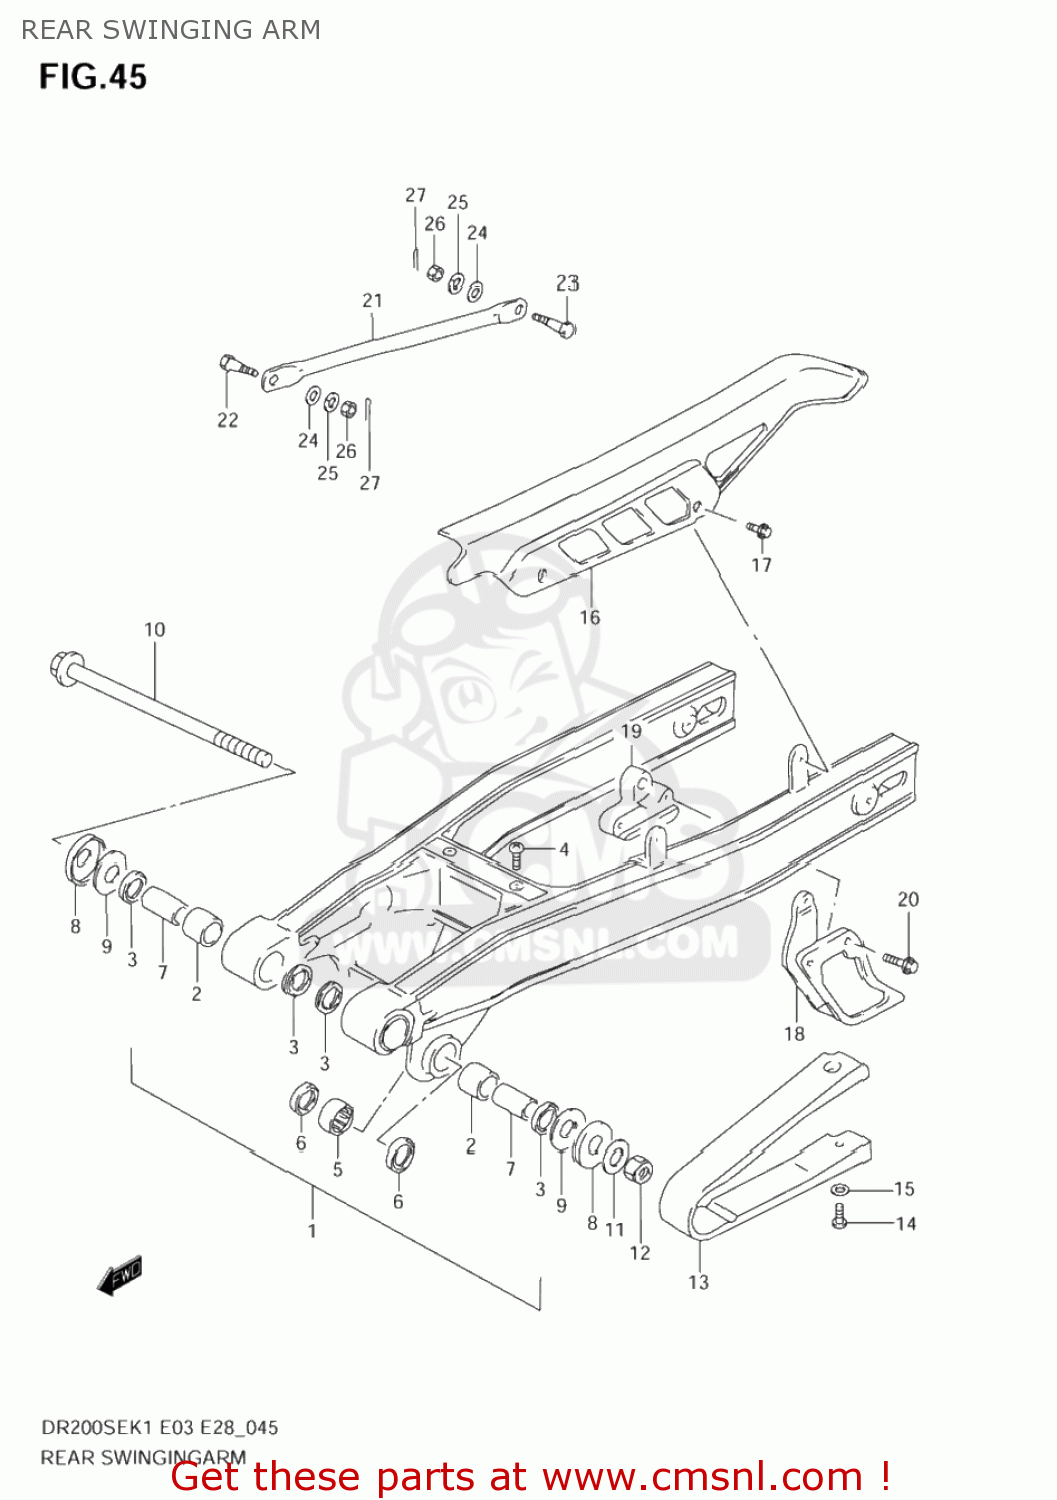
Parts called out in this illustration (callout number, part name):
1	SWINGINGARM ASSY,RR
2	BUSHING,RR SWGARM PIVOT
3	SEAL,OIL(20X27X5)
4	SCREW
5	BEARING(20X27X25)
6	SEAL,CUSHION LEVER OUT DUST
7	SPACER,RR SWGARM PVT
8	COVER,RR SWGARM DUST SEAL
9	WASHER
10	SHAFT,RR SWINGINGARM PIVOT
11	WASHER(14.5X24X2.3)
12	NUT
13	BUFFER,CHAIN TOUCH DEFENSE
14	SCREW
15	WASHER
16	CASE,CHAIN
17	BOLT(6X10)
18	GUIDE,CHAIN
19	RUBBER,CHAIN GUIDE
20	BOLT
21	TORQUELINK,RR
22	BOLT(8X28)
23	BOLT(8X26.5)
24	WASHER
25	WASHER,LOCK
26	NUT
27	PIN 20X20
